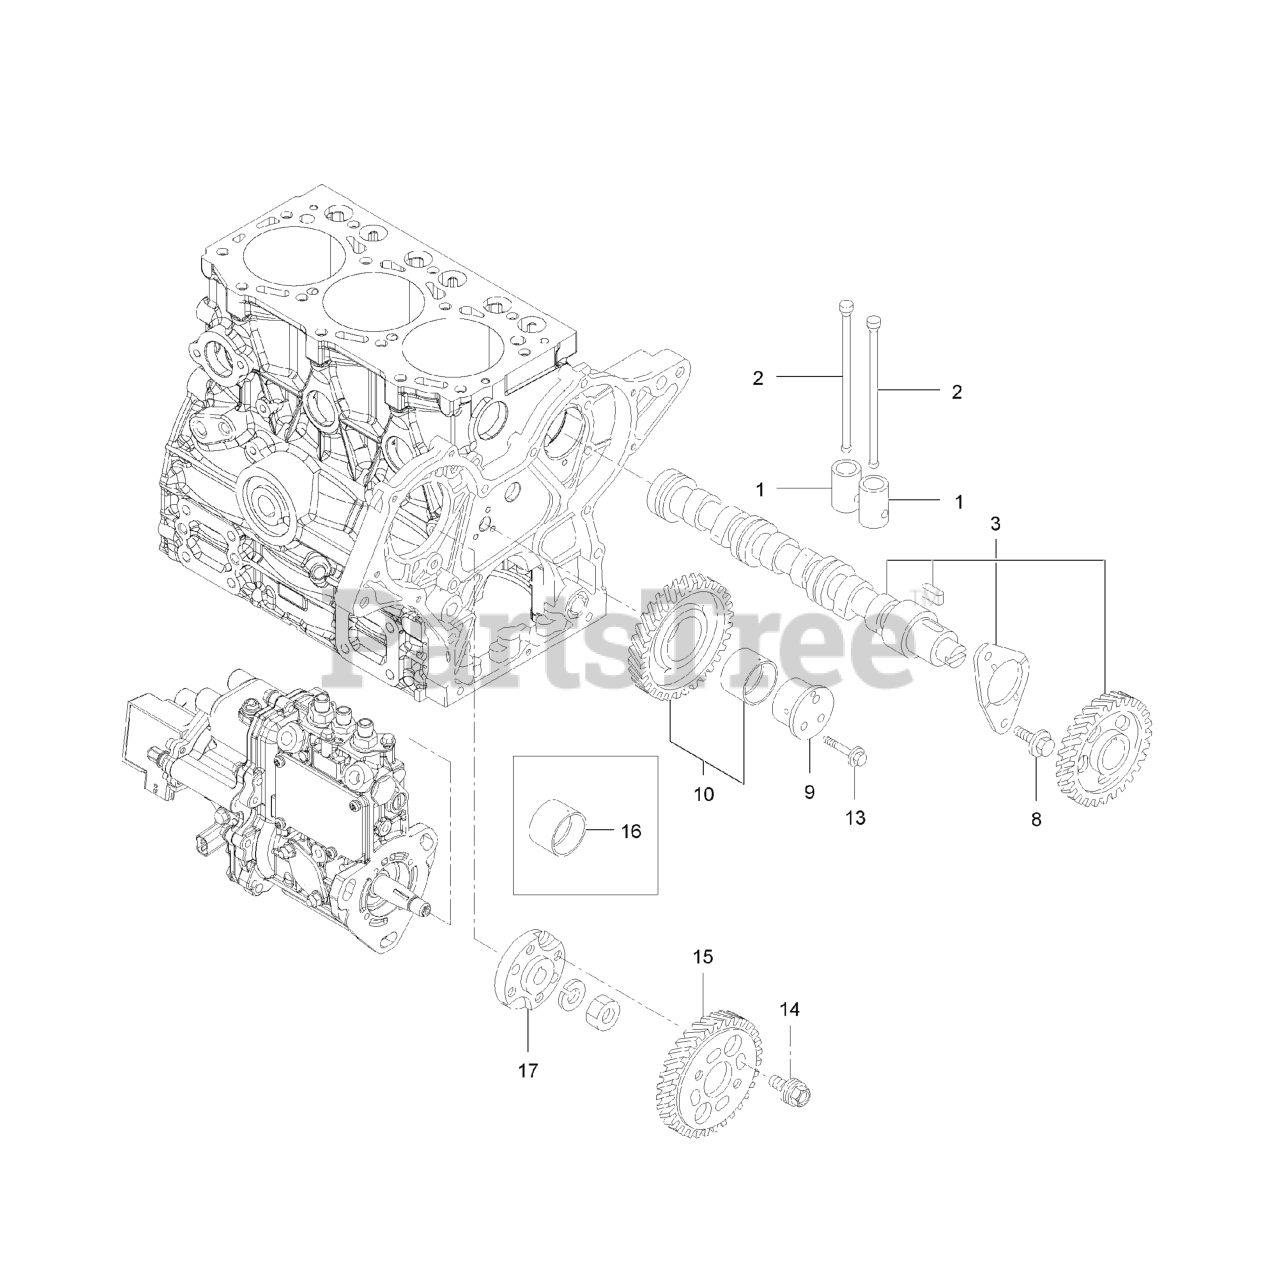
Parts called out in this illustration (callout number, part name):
2	PUSH-ROD
3	CAMSHAFT ASM
9	SHAFT-IDLE
10	GEAR ASSY-IDLE
15	GEAR-PUMP
16	BUSH-IDLE GEAR
